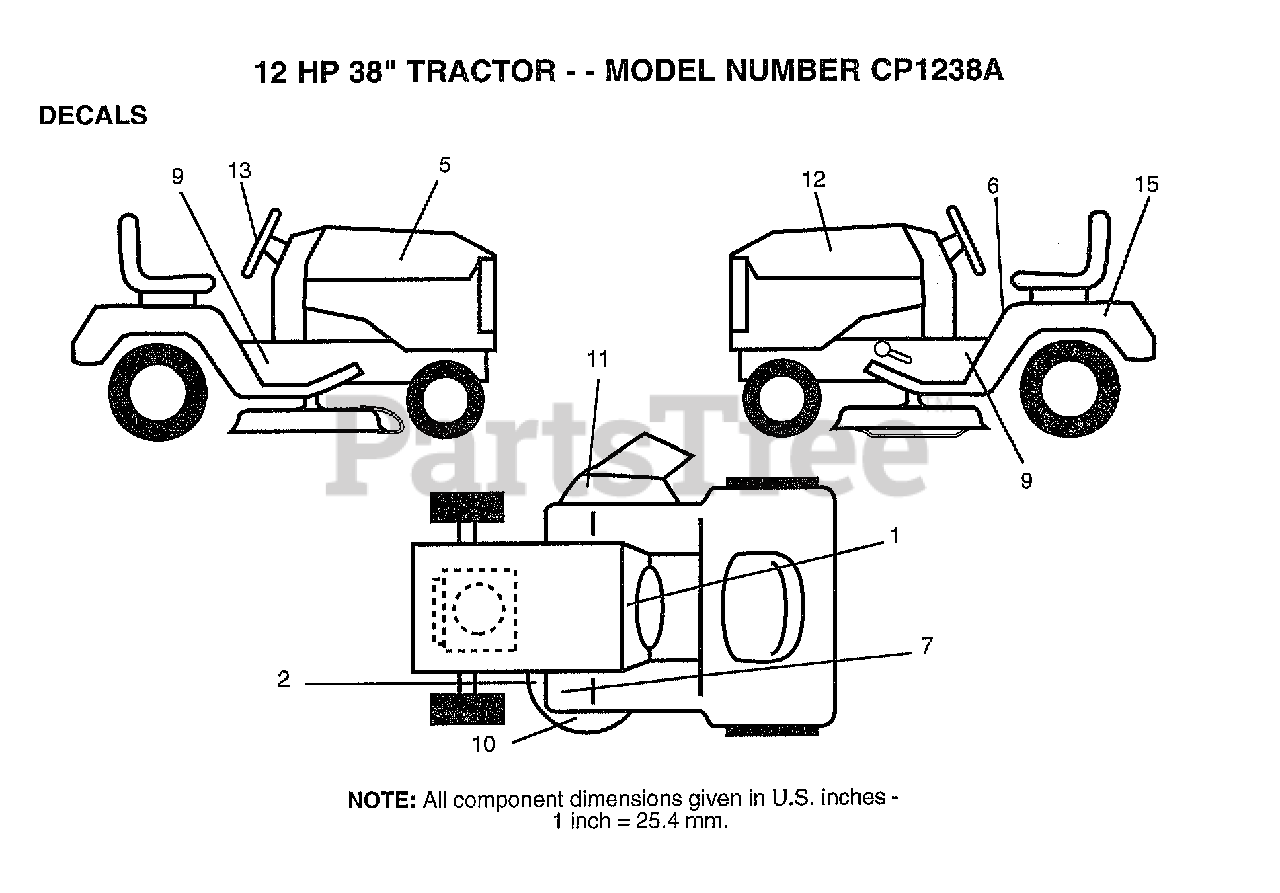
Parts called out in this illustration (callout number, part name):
1	DECAL.DASH.INSTR.
2	DECAL
5	DECAL.HOOD.RH
6	DECAL CAUTION
7	DECAL T
9	DECAL CHASSIS SPEED DECK
11	"DECAL, WARNING"
12	DECAL.HOOD.LH
15	DECAL
